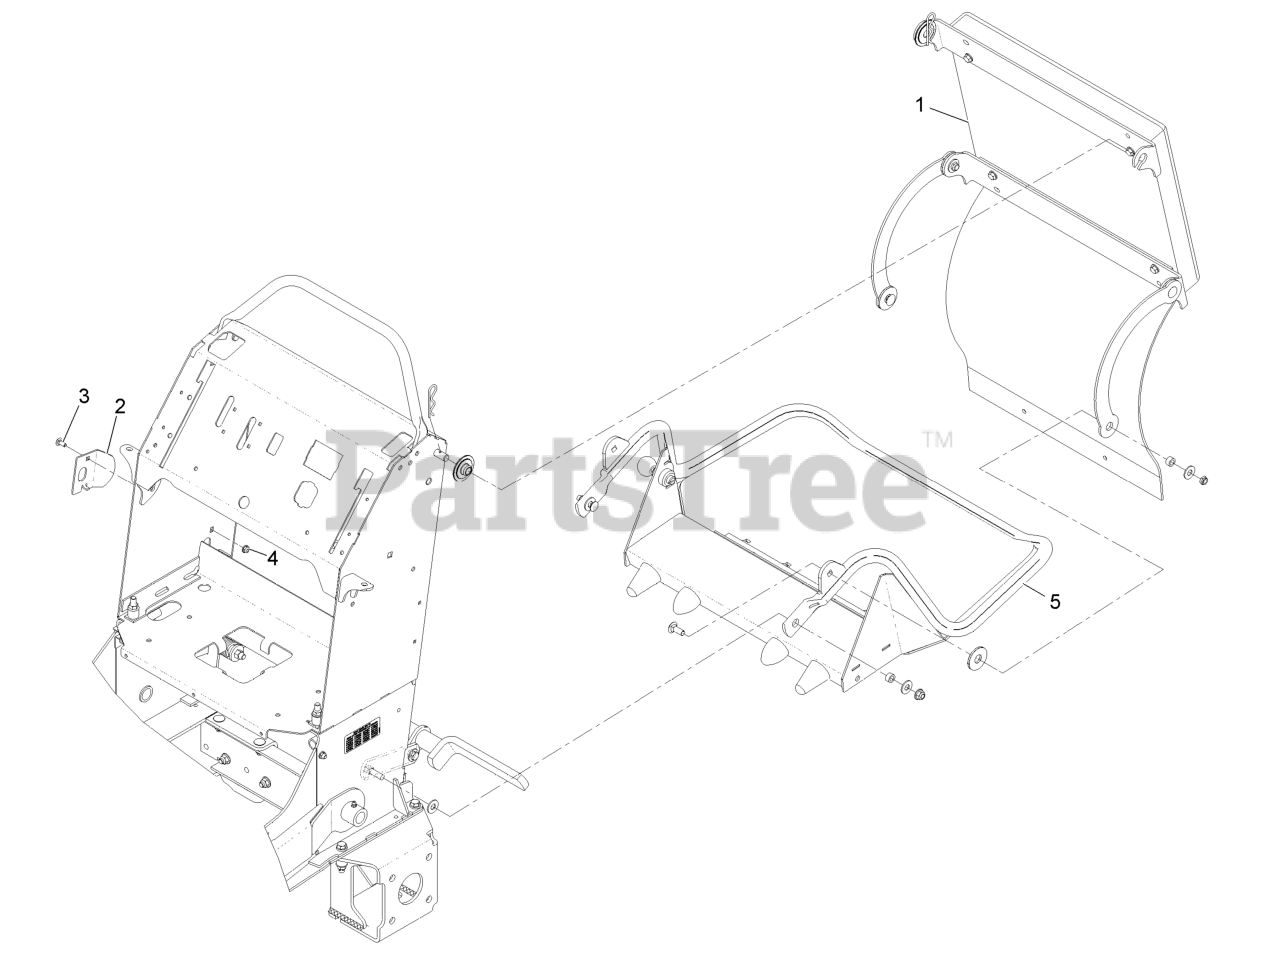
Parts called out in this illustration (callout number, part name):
2	PLATE-STRIKER
3	SCREW-CARR
5	ASM,PLATFORM
